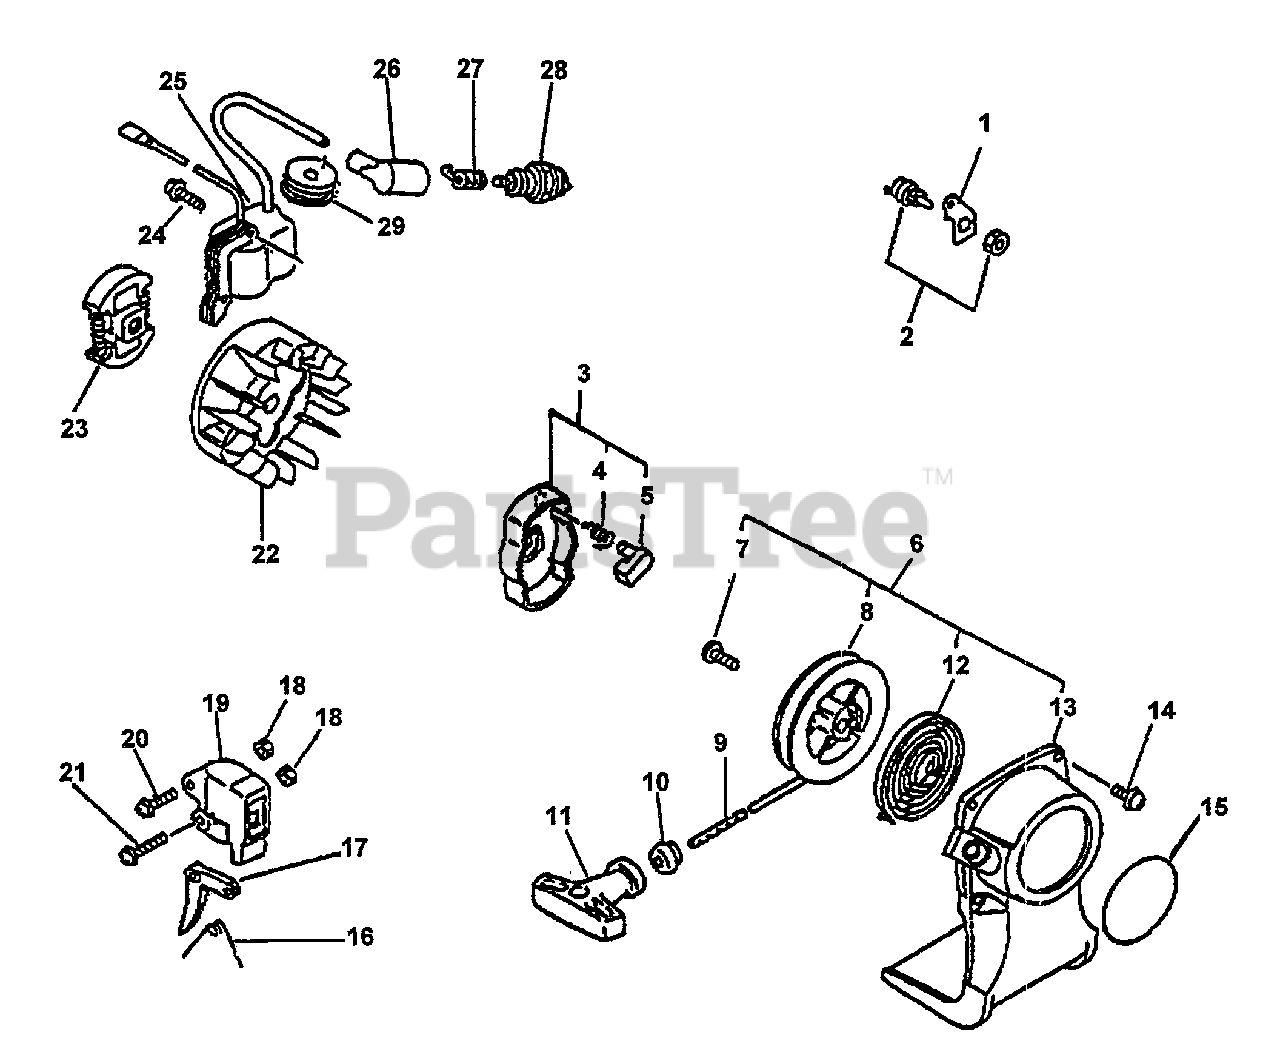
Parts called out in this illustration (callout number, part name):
1	BRACKET, SWITCH
2	SWITCH, ON-OFF
3	PAWL ASSY, STARTER
4	SPRING, RETURN
5	PAWL, STARTER - BLACK
6	STARTER ASSY
7	SCREW
8	REEL, ROPE
9	ROPE, STARTER
10	GUIDE, ROPE
11	GRIP, STARTER
12	SPRING, RECOIL
13	CASE, STARTER
14	SCREW 4×16
15	LABEL, BRAND
17	CONTROL, THROTTLE
18	NUT, LOCK M5
19	BRACKET, TRIGGER
21	SCREW 5×28
22	FLYWHEEL
23	CLUTCH ASSY
24	SCREW 4×22
25	COIL, IGNITION
26	CAP, SPARK PLUG
27	TERMINAL, SPARK PLUG
28	SPARK PLUG - BPM7A
